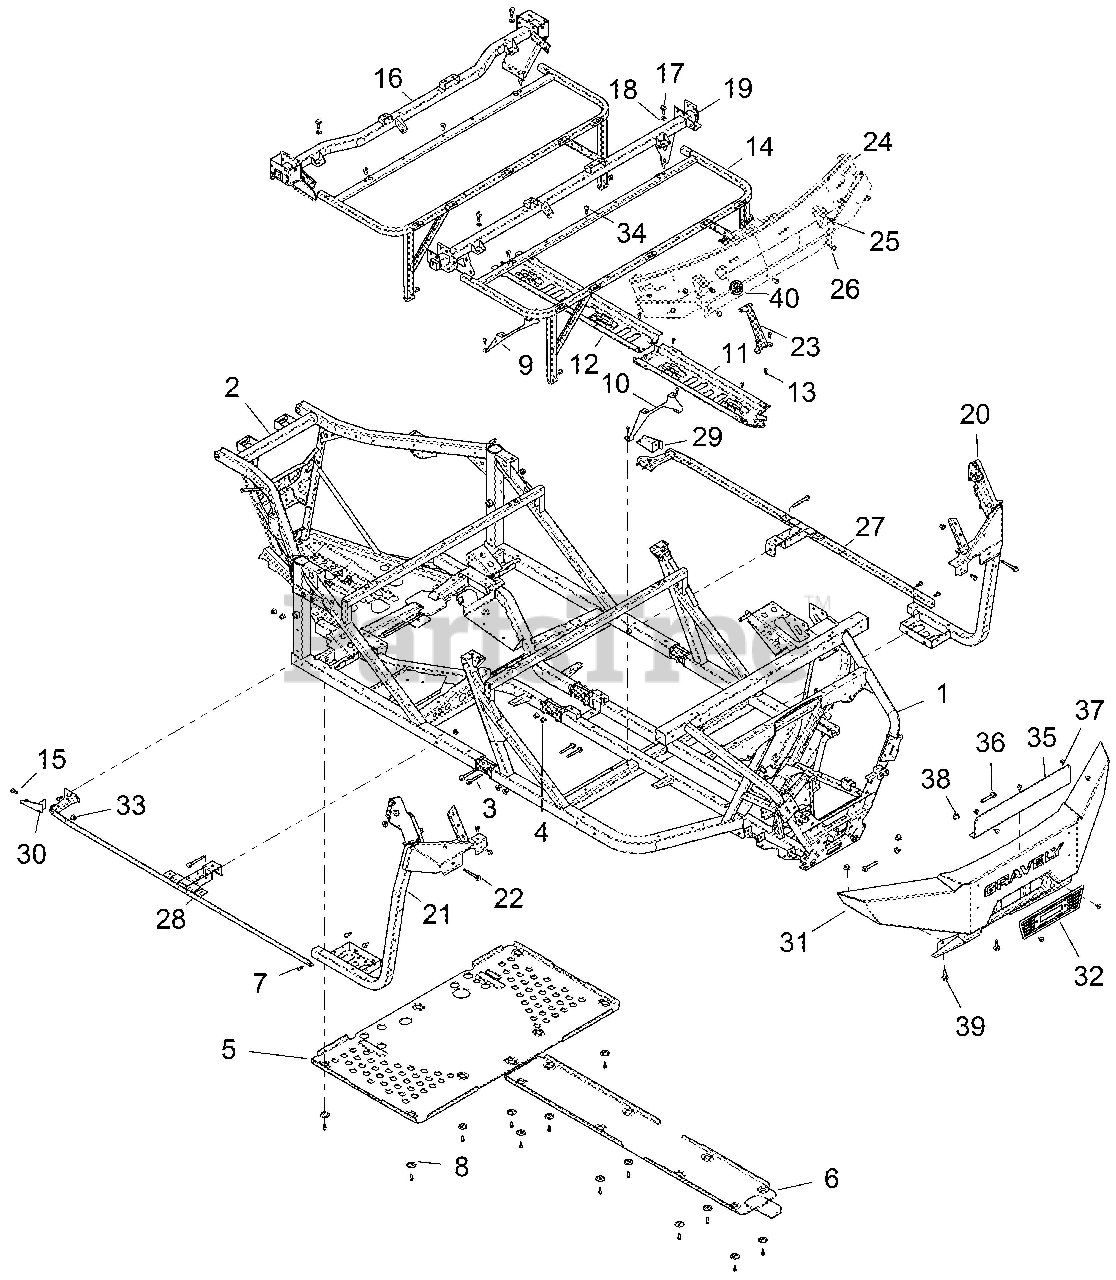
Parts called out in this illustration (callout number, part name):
1	FRAME, MAIN, FRONT, MATTE BLK
2	FRAME, REAR, MATTE BLACK
3	BOLT-M10X1.25X70,HXFLG-OLIVE D
4	NUT-M10X1.25,FLG,NYLOC-OLIVE D
5	PLATE-SKID,REAR,BLK
6	PLATE-SKID,FRONT,BLK
7	SCR-M6X1.0X20,HXHD,FLG,TDFM,BL
8	WASHER SKID PLATE
9	BRKT-ROUTING TRAY,BLK
10	BRKT-ROUTING TRAY CTR,BLK
11	TRAY-ROUTING,BLK
12	TRAY-ROUTING,REAR,BLK
13	RIVET
14	WELD-CAB/SEAT BASE,BLK
15	SCR-TXTH-M6X1.0X25 RIE
16	WELD-CAB SUPPORT,REAR,BLK
17	SCR-HXFL-M10X1.25X30 8.8 ZOD
18	WASHER,3/8 FW
19	SUPPORT, CAB, BLACK
20	WELD-FLOOR SUPPORT,LH,BLK
21	WELD-FLOOR SUPPORT,RH,BLK
22	SCR-HXFL-M10X1.25X80 8.8 ZOD
23	BRKT-PLATE,CTR,PIN MT,TTN
24	PLATE,WINDSHIELD MOUNT,LOW BLK
25	CLIP-U SPEED NUT
26	BOLT-M8X1.25X20,HXFLG,TAP/R-OD
27	WELD-ROCKER,LH,BLK
28	WELD-ROCKER,RH,BLK
29	BRACKET,SUPPORT,ROCKER,LH BLCK
30	BRACKET,SUPPORT,ROCKER,RH BLCK
31	WELD-BUMPER,FRONT,ARIENS,M BLK
32	SCREEN - BUMPER, BLK
33	NUT-M8X1.25,HXFLG,NYLON INS
34	SCR-HXFL,M8X1.25X25,ZOD,TAP/R
35	PLATE, GRAVELY RED
36	BOLT-M10X1.25X60,HXFLG-OLIVE D
37	SCR-M6X1X16 TR/TX-M
38	NUT-M10X1.25,FLG,NYLOC-OLIVE D
39	SCR-HXFL-M10X1.25X30 8.8 ZOD
40	GROMMET-ELEC,CAB,SLIT
